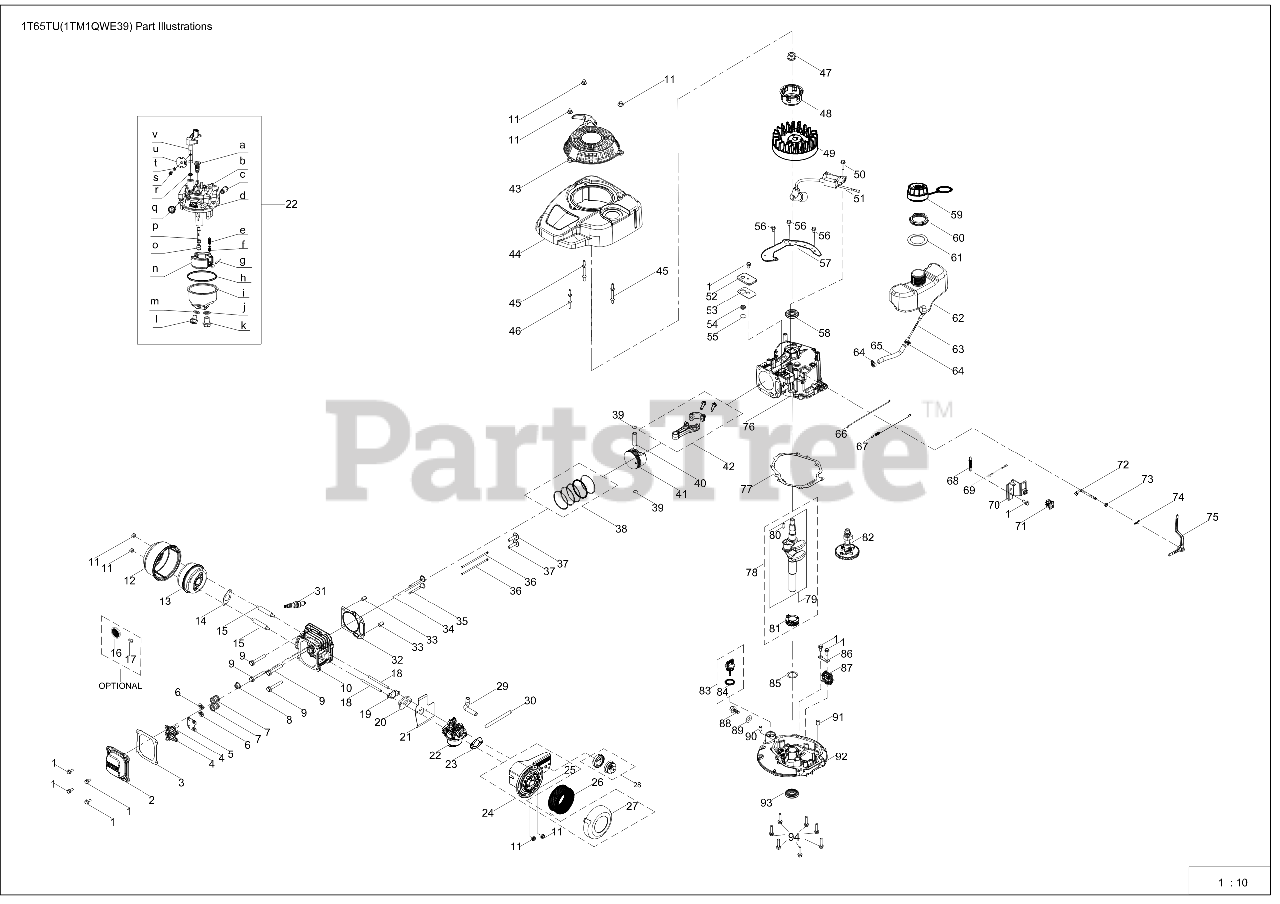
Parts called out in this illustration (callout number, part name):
1	BOLT M6-1 x 14 GR8.8
2	VALVE COVER
3	VALVE COVER GASKET
4	ROCKER ARM ASSEMBLY
5	PUSH ROD GUIDE
6	VALVE SPRING RETAINER
7	VALVE SPRING
8	INTAKE VALVE SEAL
9	SCREW M8 x 54 GR10
10	CYLINDER HEAD
11	HEX NUT
12	MUFFLER SHIELD
13	MUFFLER ASSEMBLY
14	MUFFLER GASKET
15	STUD M6-1 x 76
16	SPARK ARRESTOR
17	SCREW M3.5 x 9.5
18	STUD M6 x 98
19	CARBURETOR INSULATOR GASKET
20	CARBURETOR INSULATOR
21	CARBURETOR GASKET
22	CARBURETOR
23	AIR FILTER BASE GASKET
24	AIR FILTER ASSEMBLY
25	AIR FILTER BASE
26	PAPER AIR FILTER
26	Genuine Factory Parts AIR FILTER
27	AIR FILTER COVER
28	VENTED PRIMER ASSEMBLY
29	BREATHER HOSE
30	PRIMER HOSE
31	SPARK PLUG
32	CYLINDER HEAD GASKET
33	DOWEL PIN
34	INTAKE VALVE
35	EXHAUST VALVE
36	PUSH ROD
37	TAPPET (LIFTER)
38	PISTON RING SET
39	SNAP RING-PISTON PIN
40	PISTON
41	PISTON PIN
42	CONNECTING ROD ASSEMBLY
43	STARTER RECOIL ASSEMBLY
44	ENGINE SHROUD ASSEMBLY
45	STUD M6 x 75
46	STUD M6 x 73
47	FLYWHEEL NUT
48	START CUP
49	FLYWHEEL
50	BOLT M6-1 x 25 GR8.8
51	IGNITION MODULE
52	BREATHER COVER PLATE
53	BREATHER COVER GASKET
54	BREATHER VALVE SPRING
55	BREATHER VALVE
56	BOLT M6-1 x 10 GR8.8
57	COVER SHIELD PLATE
58	UPPER CRANKSHAFT SEAL
59	FUEL CAP W/TETHER
60	FUEL TANK NUT
61	FUEL TANK UPPER GROMMET
62	FUEL TANK
63	FUEL FILTER
63	Genuine Factory Parts FUEL FILTER
64	HOSE CLAMP
65	FUEL HOSE
66	THROTTLE LINKAGE
67	THROTTLE LINKAGE SPRING
68	GOVERNOR SPRING
69	IGNITION SWITCH
70	COMPONENT BRACKET
71	IGNITION SWITCH
72	GOVERNOR ARM SHAFT
73	GOVERNOR SEAL
74	COTTER PIN
75	GOVERNOR ARM ASSEMBLY
76	CRANKCASE
77	CRANKCASE COVER GASKET
78	CRANKSHAFT
79	CRANKSHAFT ASSEMBLY
80	FLYWHEEL KEY
81	CRANKSHAFT TIMING GEAR
82	CAMSHAFT ASSEMBLY
83	DIPSTICK ASSEMBLY
84	DIPSTICK O-RING
85	THRUST WASHER
86	GOVERNOR GEAR MOUNTING PLATE
87	GOVERNOR GEAR/SHAFT ASSEMBLY
88	OIL DRAIN PLUG
89	WASHER
90	DOWEL PIN
91	DOWEL PIN
92	CRANKCASE COVER
93	LOWER CRANKSHAFT SEAL
94	BOLT-M6-1 x 28 GR8.8
